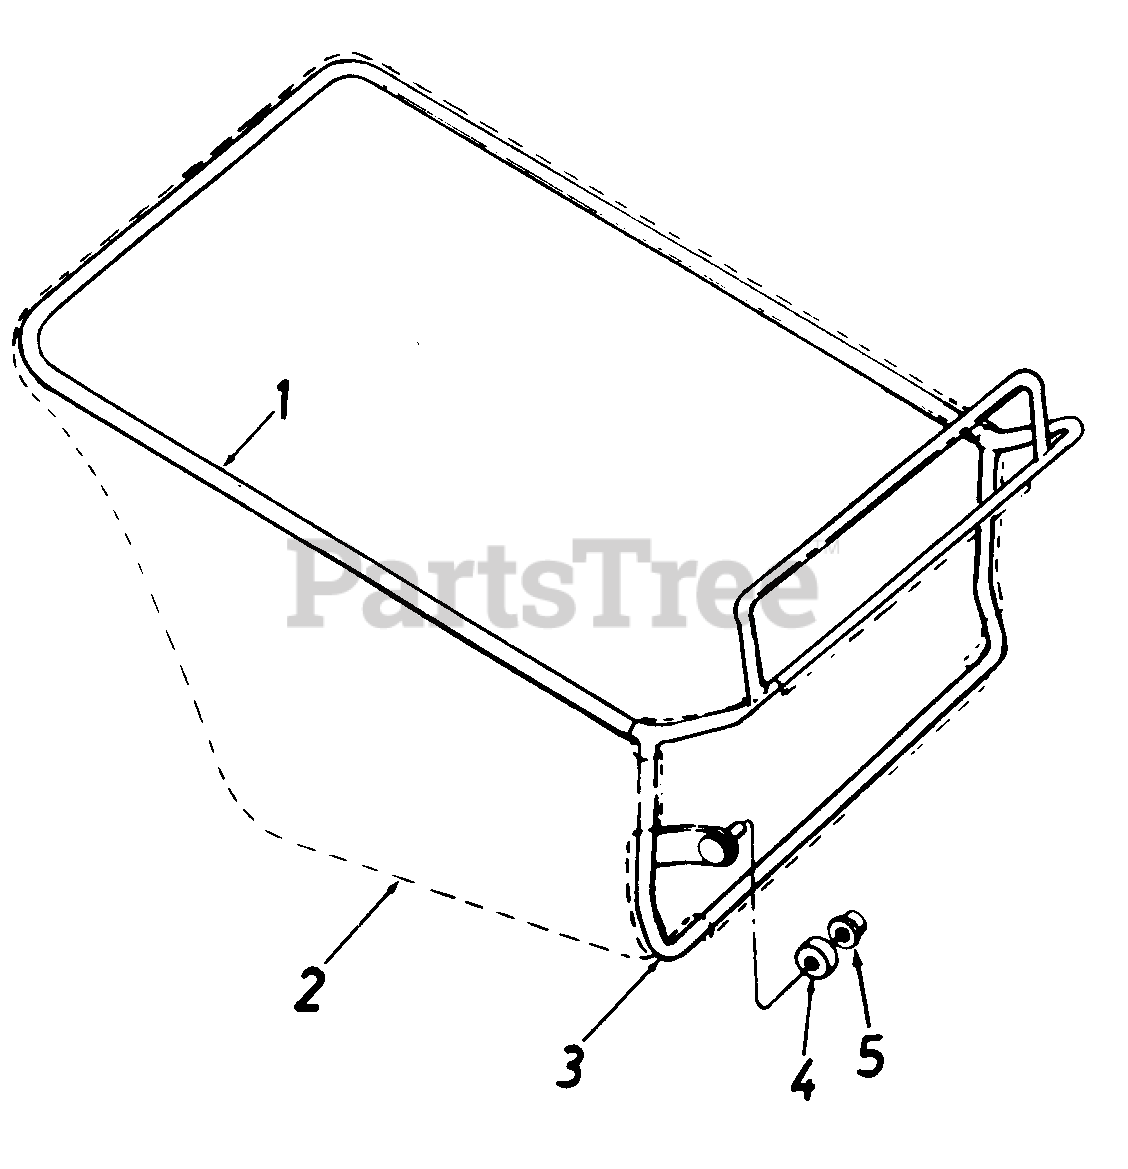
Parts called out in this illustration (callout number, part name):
1	Upper Frame
2	Grass Bag
5	Push Can
